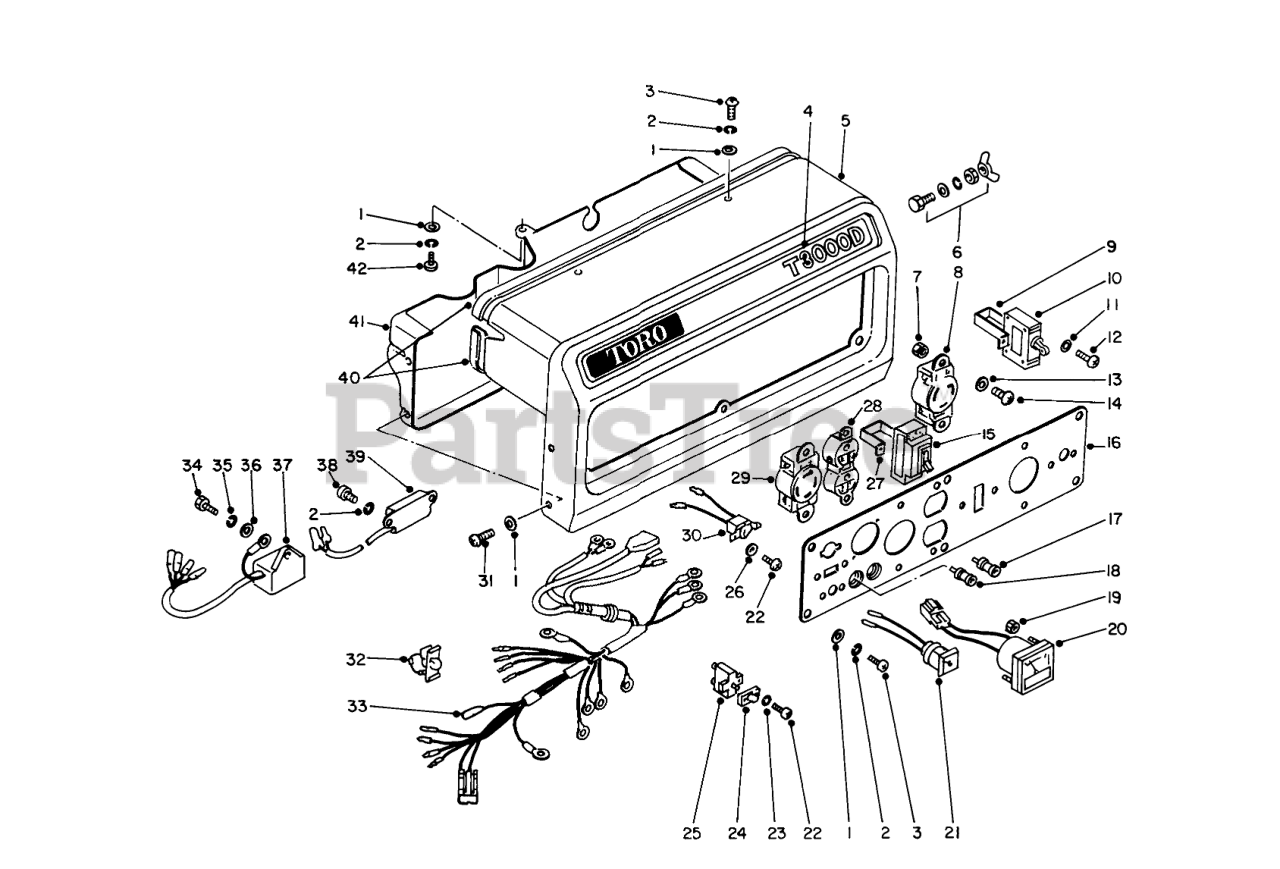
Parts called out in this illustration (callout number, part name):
8	Receptacle (125V, 30A)
29	Receptacle
35	LOCKWASHER
